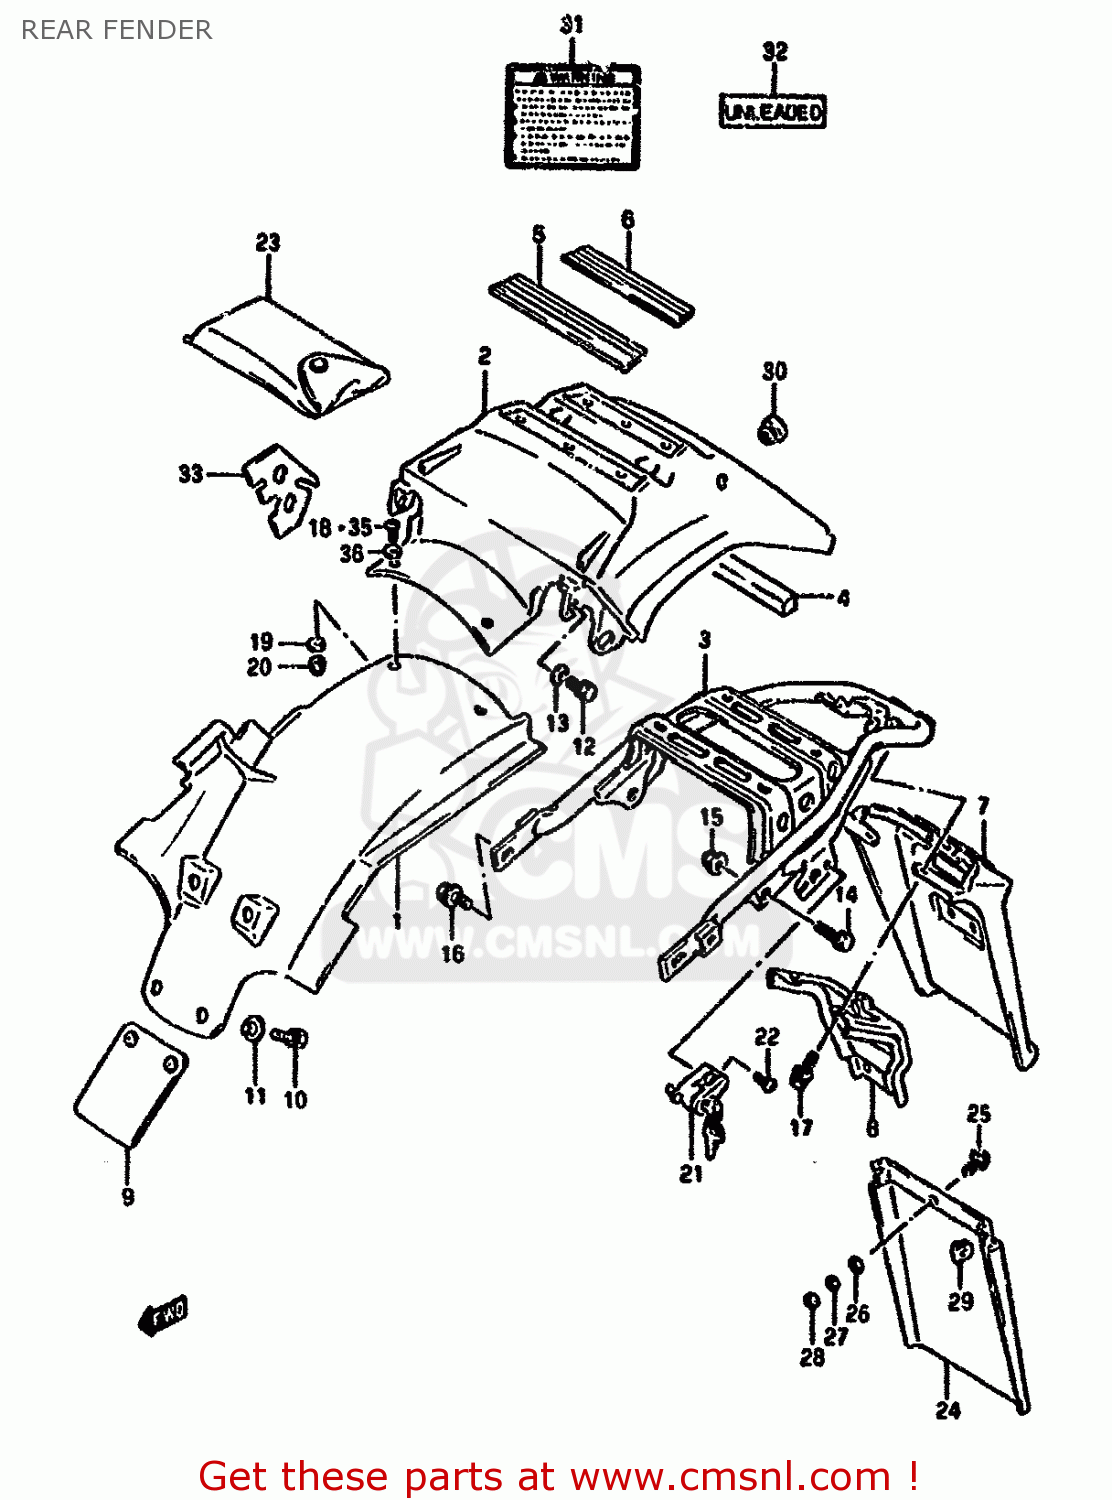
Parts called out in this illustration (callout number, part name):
1	BODY,REAR FENDER,FRONT
2	BODY,REAR FEND
3	REINFORCEMENT,REAR FENDER
4	CUSHION,REAR FENDER &
5	CUSHION,REAR FENDER,REAR
6	CUSHION,REAR FENDER,REAR
7	EXTENSION,RR FENDER
8	REINFORCEMENT,EXTENSION
9	GUARD,RR FENDER FR MUD
10	BOLT
11	WASHER
12	BOLT
13	WASHER
14	BOLT
15	NUT
16	BOLT(8X16)
17	BOLT(6X20)
18	SCREW
19	WASHER (5.5X16X1.2)
20	NUT
21	LOCK SET,HELMET
22	SCREW
23	TOOL ASSY
24	MUDGUARD,RR FENDER RR
25	SCREW, LOWER
26	WASHER
27	LOCK WASHER
28	NUT
29	NUT
30	CAP(OD:20)
31	LABEL, WARNING
32	LABEL,CAUTION
33	SHIELD,REAR FENDER,REAR
34	LABEL,TIRE AIR PRESSURE
35	SCREW
36	WASHER (5.5X16X1.2)
